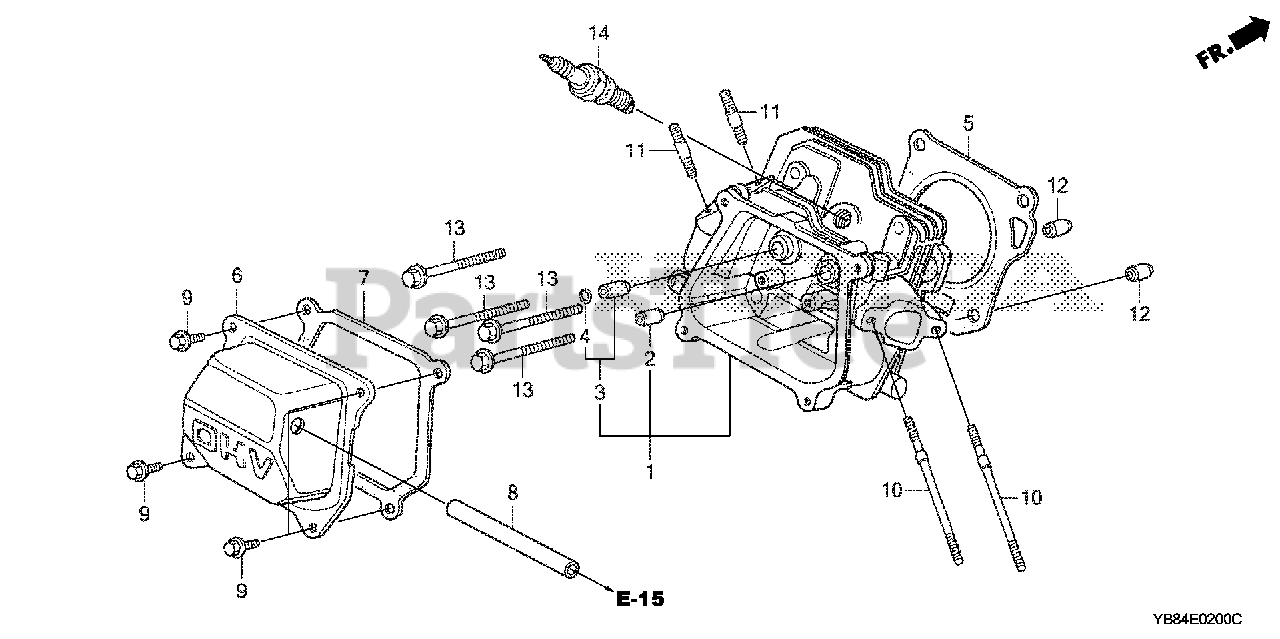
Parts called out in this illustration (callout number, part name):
1	CYLINDER HEAD
2	GUIDE, VALVE (OVER SIZE) Use from Engine SN 6324986.
3	GUIDE, EX. VALVE (OS)
4	CLIP, VALVE GUIDE Use from Engine SN 1231803.
5	GASKET, CYLINDER HEAD (NIPPON LEAKLESS)
6	COVER, HEAD
7	GASKET, CYLINDER HEAD COVER
7	GASKET, HEAD COVER
8	TUBE, BREATHER
9	BOLT, FLANGE (6X12) (CT200)
10	BOLT, STUD (6X109)
11	BOLT, STUD (8X32)
12	PIN A, DOWEL (10X16)
13	BOLT, FLANGE (8X60)
14	SPARK PLUG (BPR6ES) (NGK)
14	SPARK PLUG (W20EPR-U) (DENSO)
